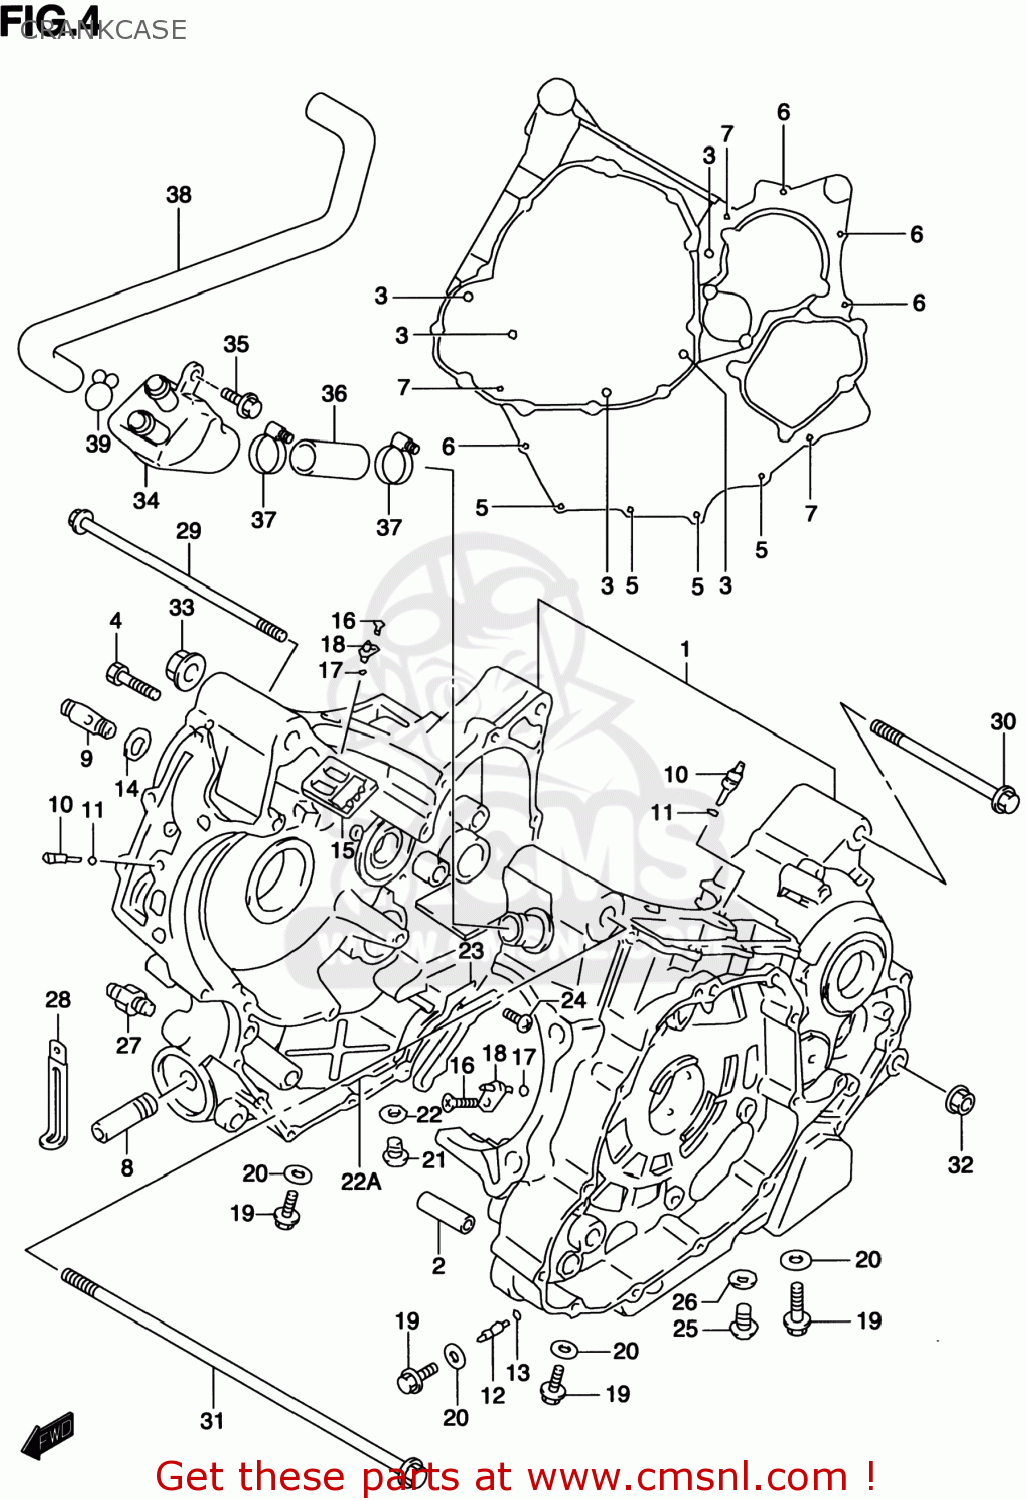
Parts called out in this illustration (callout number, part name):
1	CRANKCASE SET
2	PIN,CRANKCASE
3	BOLT
4	BOLT
5	BOLT
6	BOLT
7	BOLT
8	UNION,OIL STAND
9	JET,OIL GALLERY(3.6)
10	JET,OIL GALLERY
11	O RING(D:1.2,ID:4)
12	JET,AIR(14)
13	O RING(D:1.2,ID:4)
14	O RING(D:1.9,ID:12.6)
15	VALVE ASSY,BREATHER
16	SCREW(6X12)
17	O RING(D:1.2,ID:4)
18	JET,PISTON COOLING
19	BOLT
20	GASKET(8.2X14X1).6 (NAS)
21	PLUG,16X8
22	GASKET(16X22X2) (NAS)
22A	SEPARATOR,OIL
23	COVER,OIL GALLERY
24	SCREW
25	PLUG
26	GASKET(13.8X18.8X4.8) (NAS)
27	SWITCH ASSY,OIL PRESSURE
28	CLAMP(L:45)
29	BOLT(10X205)
30	BOLT(10X155)
31	BOLT(12X340)
32	NUT
33	NUT 12MM
34	TANK,OIL RETURN
35	BOLT
36	HOSE, OIL RETU
37	CLAMP
38	HOSE,BREATHER
39	CLIP
